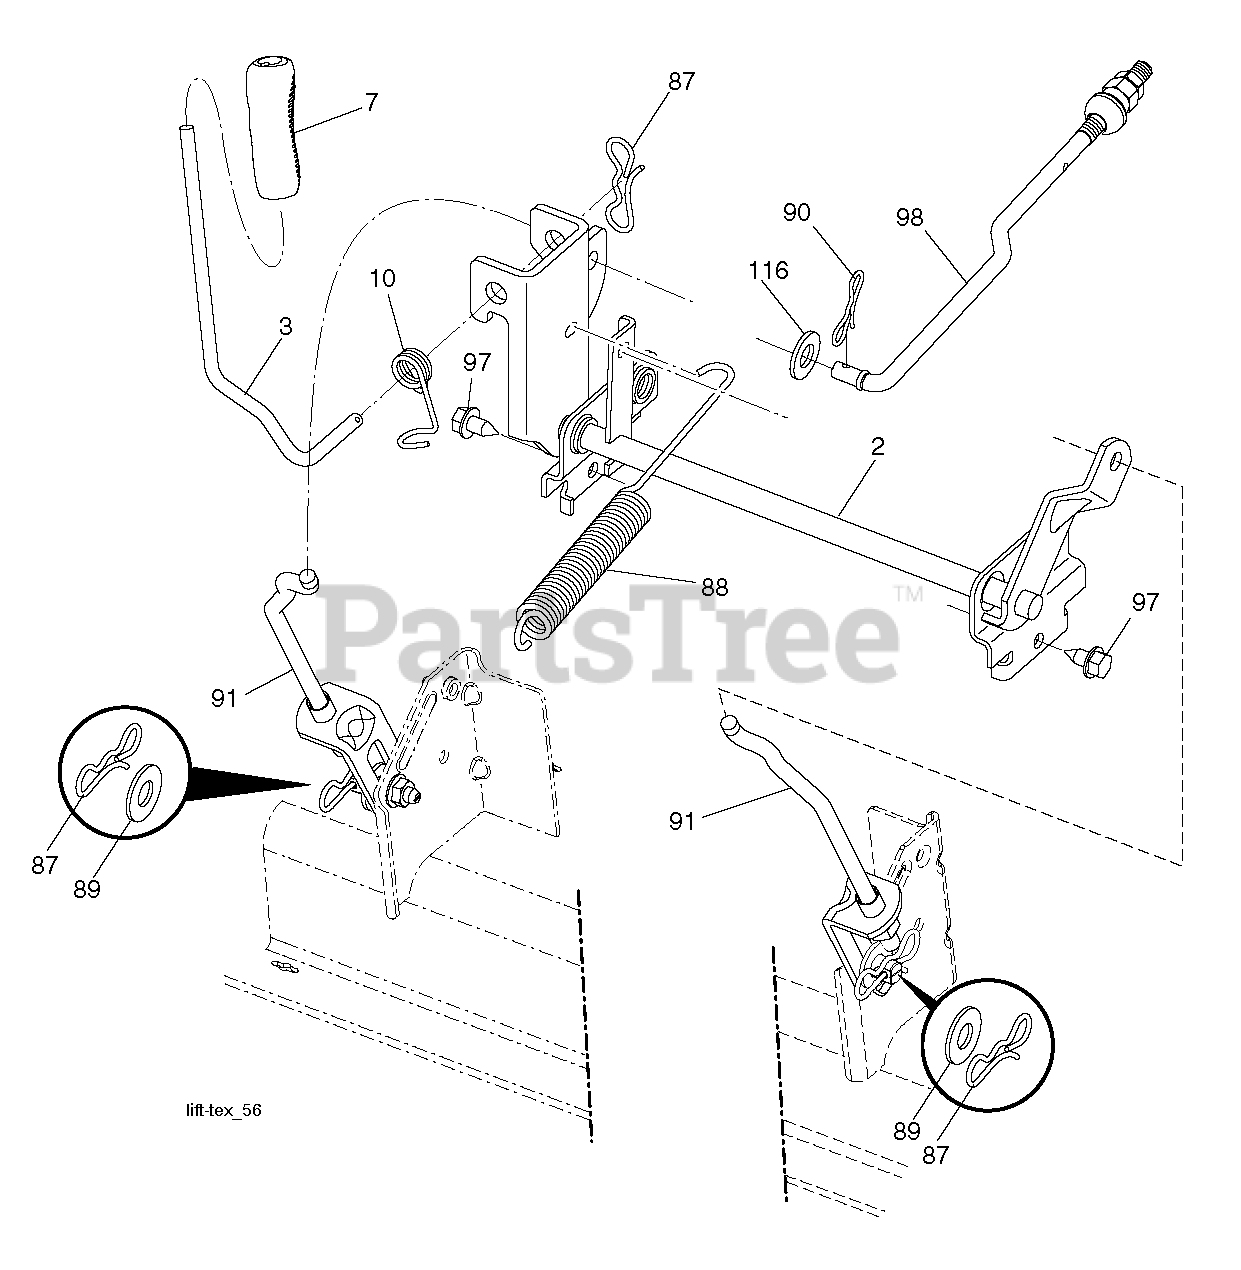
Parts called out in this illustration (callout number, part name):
2	SHAFT.ASM.CROSS.LIFT
3	LEVER.LIFT.HANDLE.LT
7	GRIP.HANDLE.LIFT.PVC.BLACK
10	SPRING.TORSION.LIFT.HANDLE
87	PIN.COTTER.7/16.BOW TI.
88	SPRING.LIFT.ASSIST
89	WASHER.CLEAR.ZINC
90	PIN.COTTER.5/16.BOW TI
91	LINK.LIFT.ASM.REAR.GT.
97	SCREW, 3/8-16X3/4
98	LINK.FRONT.MOWER.SUSP.ASM.BLK
